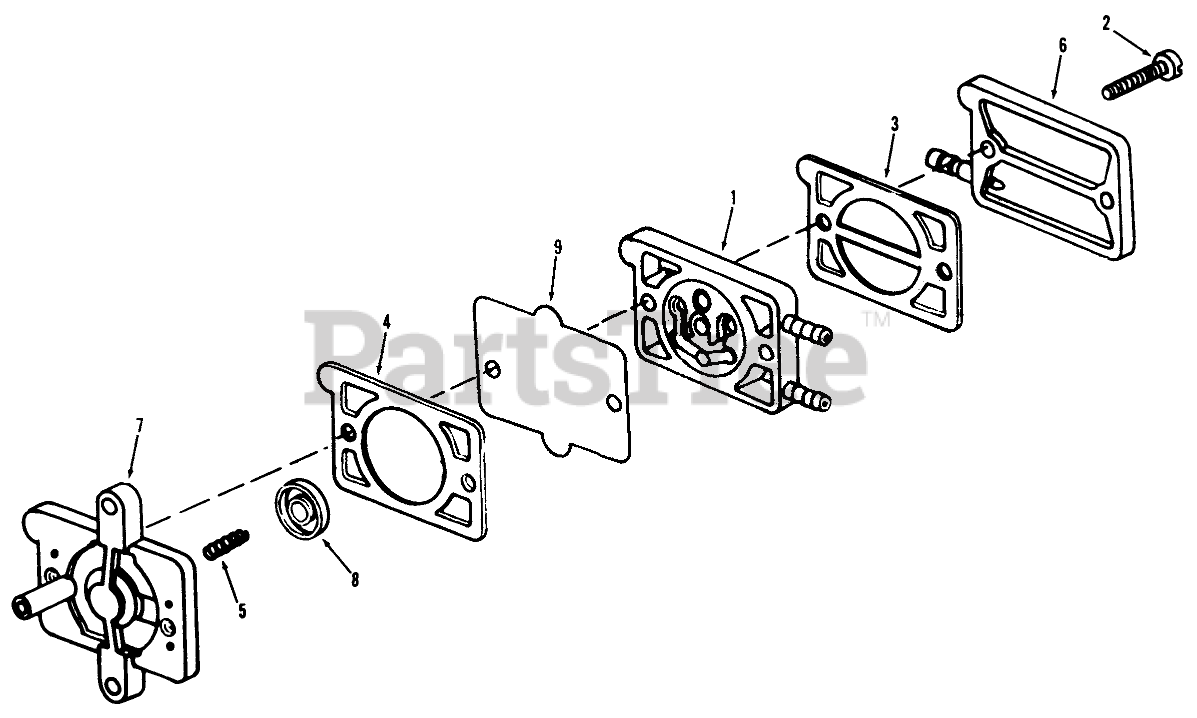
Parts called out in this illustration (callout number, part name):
1	Valve Plate Assy
2	Screw-Pump Cover
3	Gasket-Cover To Valve Plate
4	Gasket-Base To Diaphram
5	Spring-Pump To Diaphram
6	Cover-Pump
7	Base Pump
8	Plate-Pump Spring
9	Pump Diaphragm
